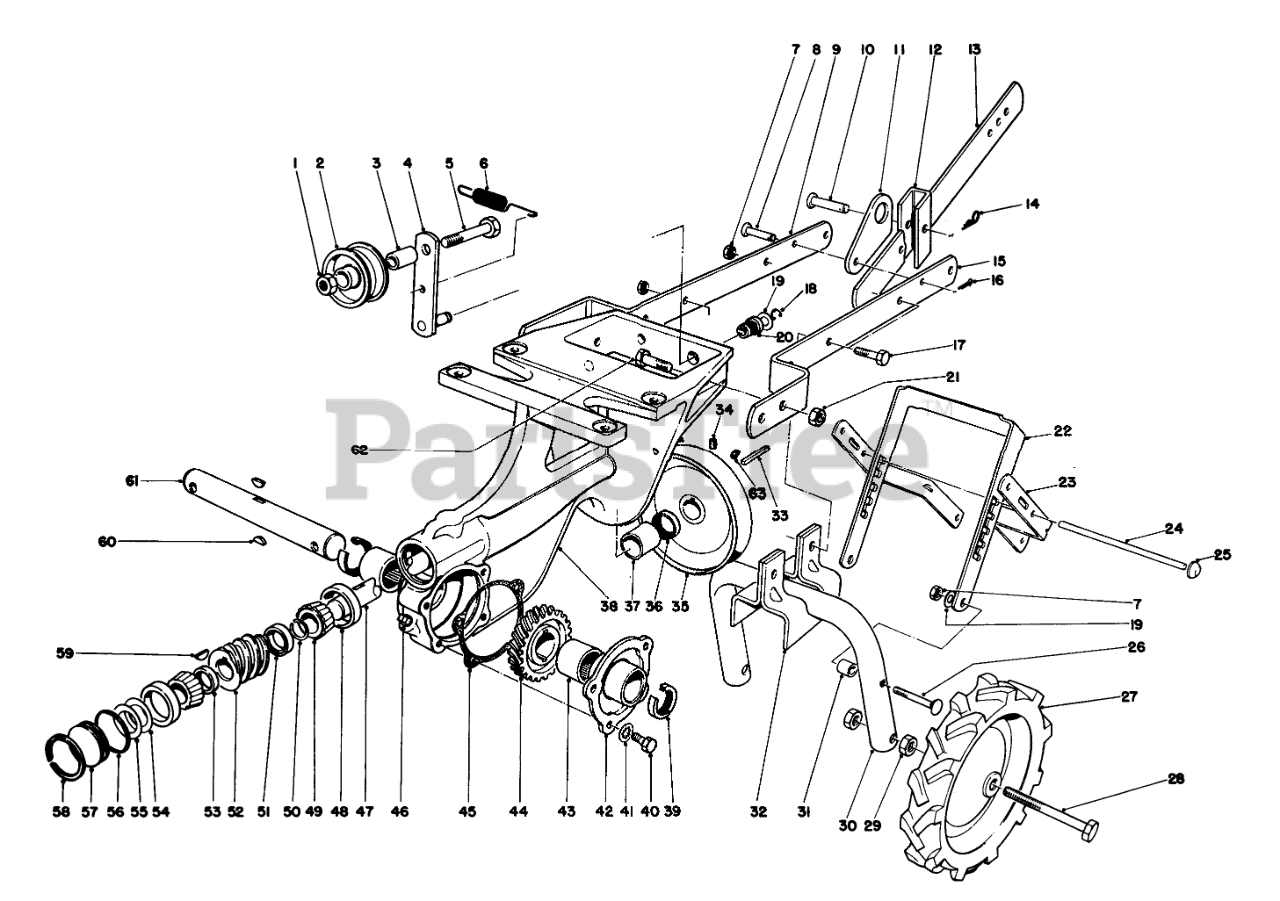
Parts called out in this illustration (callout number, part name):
1	NUT-LOCK, CONE
2	PULLEY IDLER
3	Spacer
4	Idler Arm
5	SCREW-HH
6	TENSION SPRING
7	NUT-LOCK, CONE
8	PIN-CLEVIS
9	Drawbar R.H.
10	CLEVIS
11	Latch-Depth Gauge
12	DEPTH GUAGE BRKT
13	Depth Gauge
14	PIN-COTTER, HAIR
15	Drawbar L.H.
16	PIN-COTTER
17	SCREW-HH
18	RING-RETAINING, EXT
19	WASHER-PLAIN
20	IDLER BRG
21	NUT-KEPS
22	Lever Wheel Adjustment
23	HANDLE SUPPORT
24	Shaft-Wheel Adjustment
25	PUSH ON
26	BOLT-CARR
27	Wheel
28	Wheel Bolt
29	Locknut
30	Axle Yoke
31	Spacer
32	Saddle Yoke
33	KEY-SQUARE
34	SCREW-SET, SQH
35	Pulley-Oil Seal
36	SEAL-OIL
37	BUSHING
38	Chassis
39	SEAL-OIL
40	1/4-20 X 5/8 CAPSCREW
41	WASHER-LOCK
42	Cover
43	Needle Bearing
44	WORM WHEEL
45	GASKET
46	PLUG-PIPE, SQH
47	WORM SHAFT
48	BEARING-ROLLER, CUP
49	BEARING-CONE
50	RETAINER RING
51	Spacer Rear
52	WORM GEAR
53	SPACER
56	O-RING
58	INTRNL RETAINING RING
59	KEY-WOODRUFF
60	KEY-WOODRUFF
61	WORM WHEEL SHAFT
62	SCREW-HH
63	SCREW-SQH
